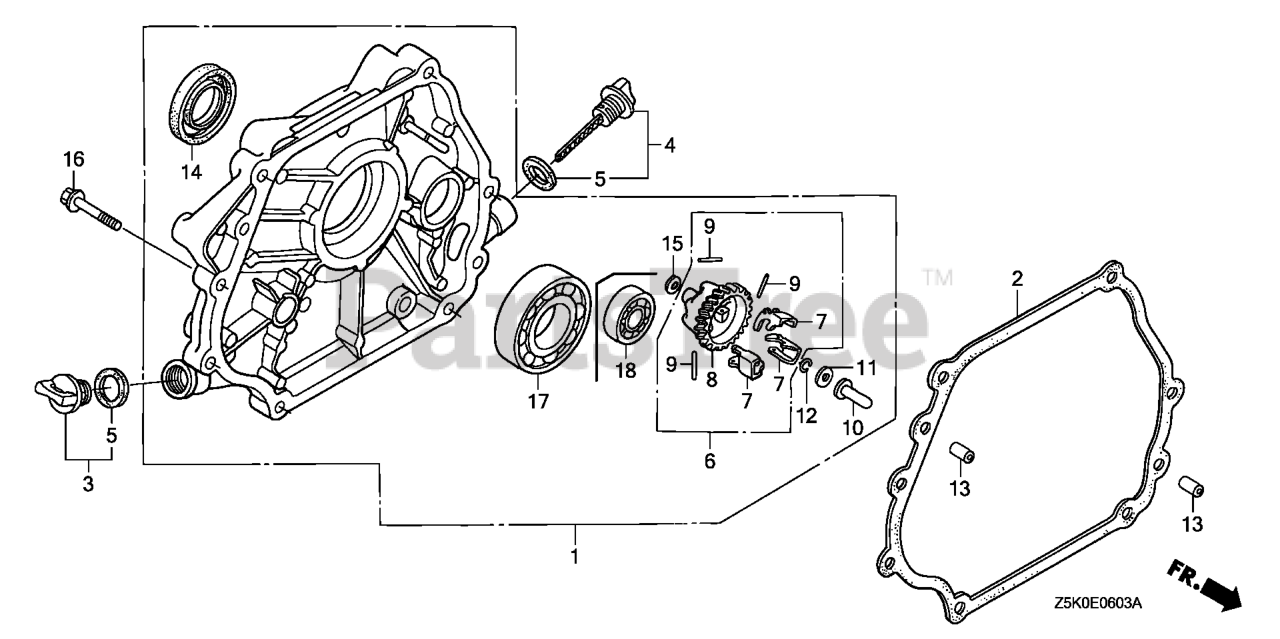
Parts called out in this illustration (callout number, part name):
1	COVER ASSY., CRANKCASE
2	GASKET, CASE COVER
3	CAP ASSY., OIL FILLER
4	CAP ASSY., OIL FILLER
5	GASKET, OIL FILLER CAP
6	GOVERNOR ASSY.
7	WEIGHT, GOVERNOR
8	HOLDER, GOVERNOR WEIGHT
9	PIN, GOVERNOR WEIGHT
10	SLIDER, GOVERNOR
12	CLIP, GOVERNOR HOLDER
13	PIN, DOWEL (8X12)
14	OIL SEAL (30X46X8) (NOK ASIA)
15	WASHER, PLAIN (6MM)
16	BOLT, FLANGE (8X35)
17	BEARING, RADIAL BALL (6206)
18	BEARING, RADIAL BALL (6202)
